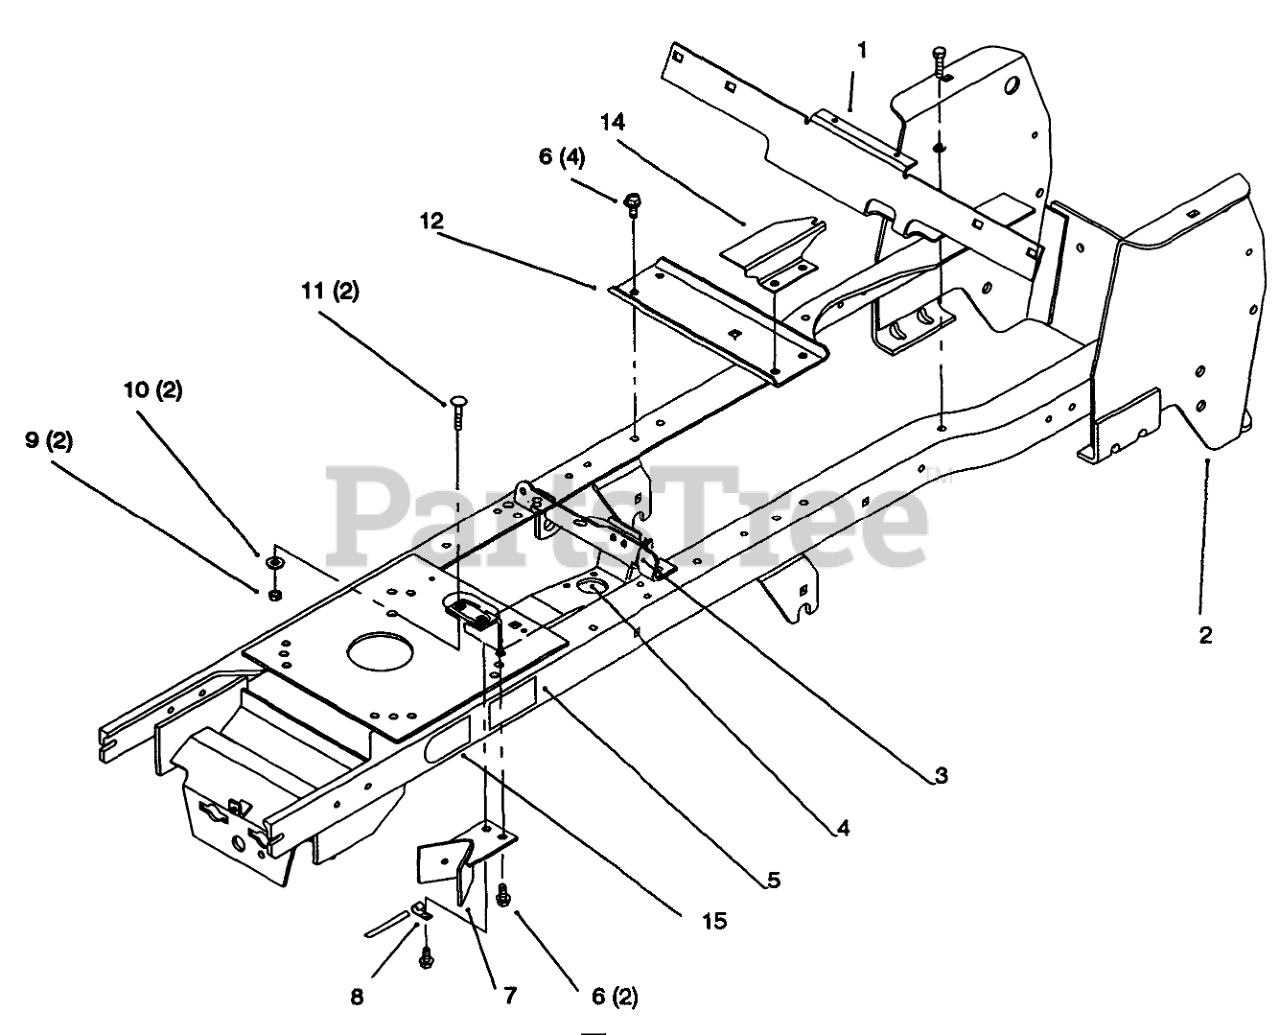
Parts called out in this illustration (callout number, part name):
1	SUPPORT - FENDER
2	FRAME WA BLACK
3	TIE-CABLE
4	STEERING BRKT WA
5	Decal-Belt Install (Only On: 72042, 72043, 72083)
5	Decal-Belt Install (Only On: 72103, 72063, 72062)
6	SCREW-HWHTF
7	WLDMT-PTO STOP
8	CLIP
9	NUT-LOCK, NI
10	WASHER-PLAIN
11	BOLT-CARR
12	BRACKET-IDLER PLATE
14	BRACKET-HOC GAGE
15	DECAL-ATTACH A-MATIC
